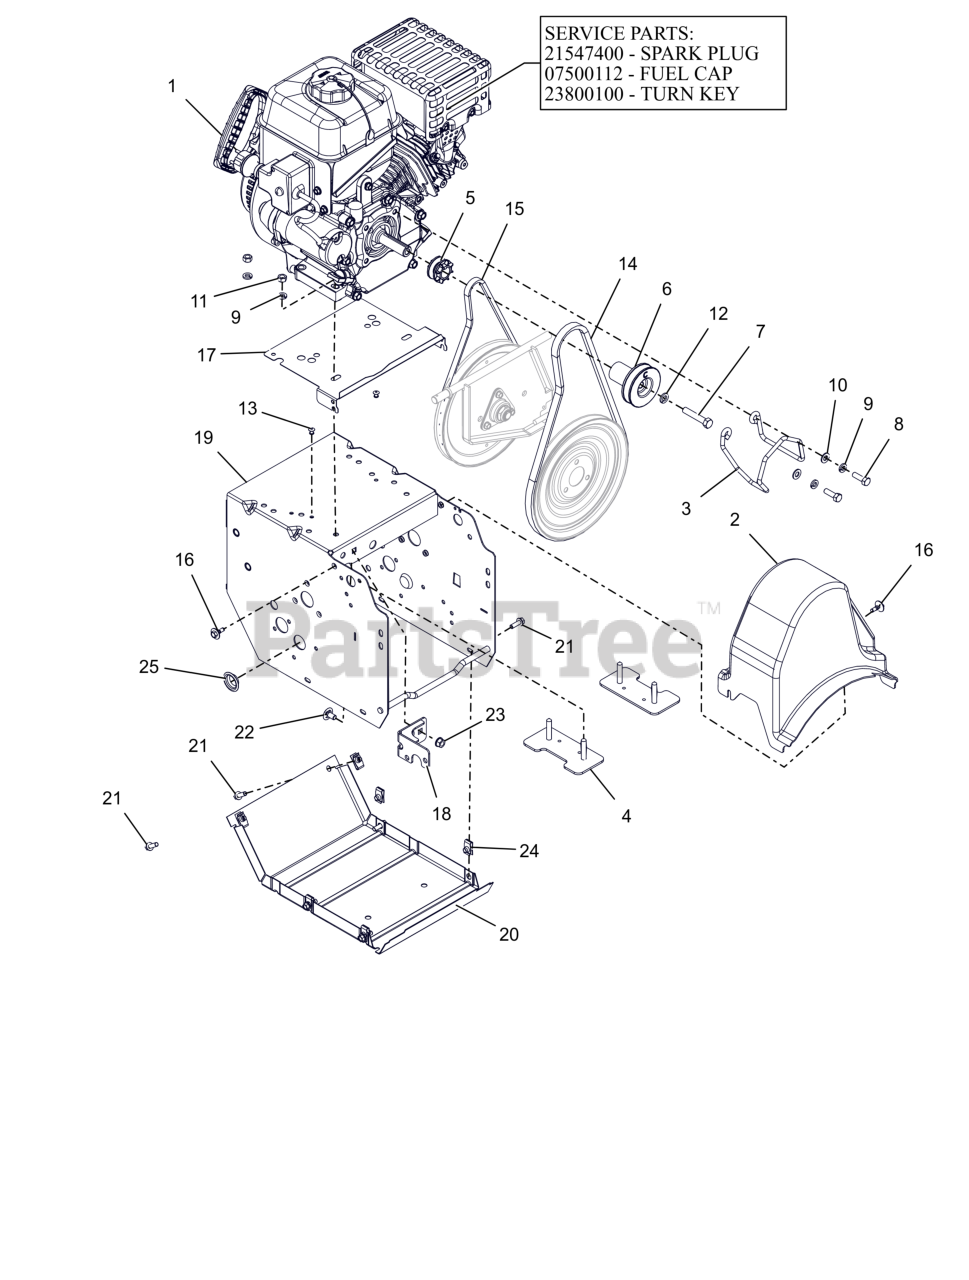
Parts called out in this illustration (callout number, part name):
1	ENGINE, ARIENS AX208 120V
1	PLUG, SPARK
1	CAP, FUEL TANK BLACK
1	KEY, TURN LCT (2/PACKAGE)
2	COVER, COMPACT BELT
3	FINGER, BELT
4	STRAP, ENGINE BOLT-WELDMENT
5	SHEAVE, TRACTION
6	SHEAVE, ATTACHMENT SINGLE GRV
7	BLT, HEX .38-24X2.00 G5 ZCC
8	BLT, HEX 0.3125-24X1 G5 ZCC
9	WSHR, LK-HVY .312X.097 ZCC
10	WSHR,FLT .344X.688X.065 ZCC
11	NUT, HEX .312-18 ZCC
12	WSHR,LK-REG .375X.094 ZCC
13	RVT, POP .1875 ZCC
14	V-BELT, HA-RAW EDGE
15	V-BELT, 3L-WRAPPED
16	SCR-TAP .25-20X.5 CAPTIVE
17	BAFFLE, COMPACT
18	WELDMENT, FRAME BRACKET
19	FRAME, MAIN
20	COVER, BOTTOM
21	BLT, HWH .25-20X.75 G5 ZCC
22	BLT, RHSSN .31-18X.625 G5 ZCC
23	NUT-LK-TOP-FLG .312-18 GF ZCC
24	NUT-RTNR .25-20X.56
25	PLUG, HOLE - 1.00" FLEXTEMP
